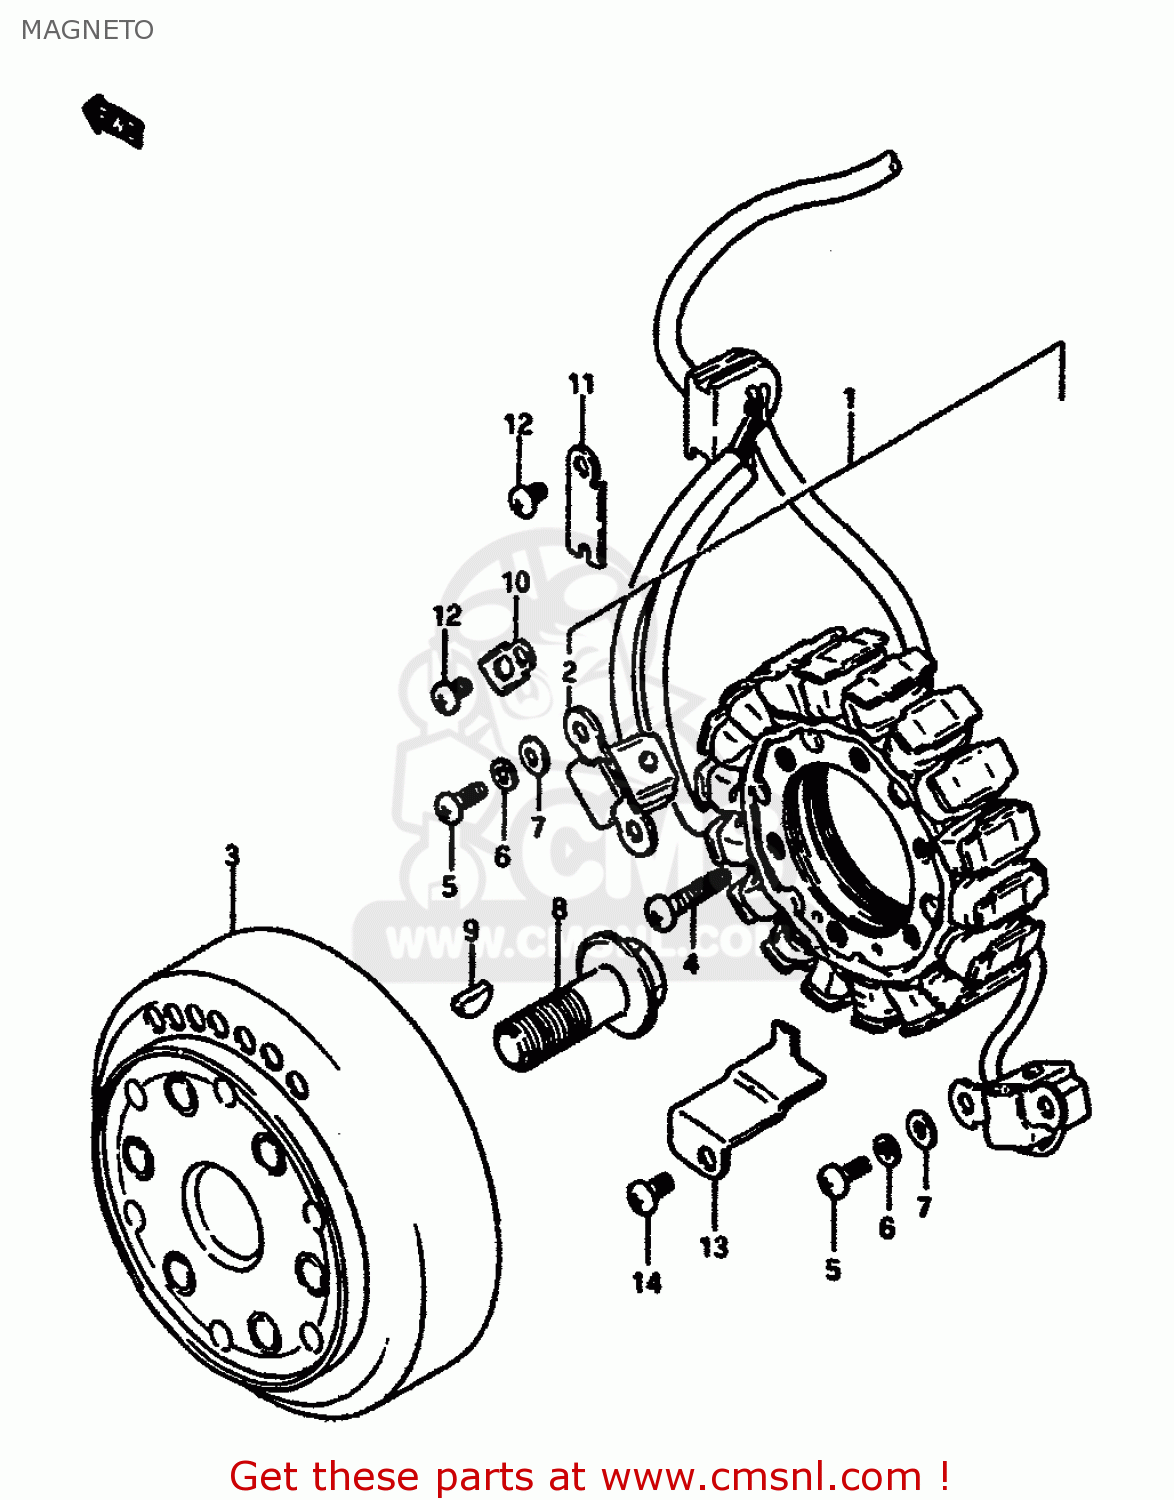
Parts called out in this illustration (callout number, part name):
1	STARTER ASSY
2	SENSOR & WIRE ASSY
3	ROTOR
4	BOLT
5	SCREW
6	WASHER
7	LOCK WASHER
8	BOLT(14X43)
9	KEY 4MM
10	CLAMP,GENERATOR LEAD WIRE
11	CLAMP NO.1,MAGNETO READ WIRE
12	SCREW
13	CLAMP,MAGNETO LEAD WIRE
14	BOLT
